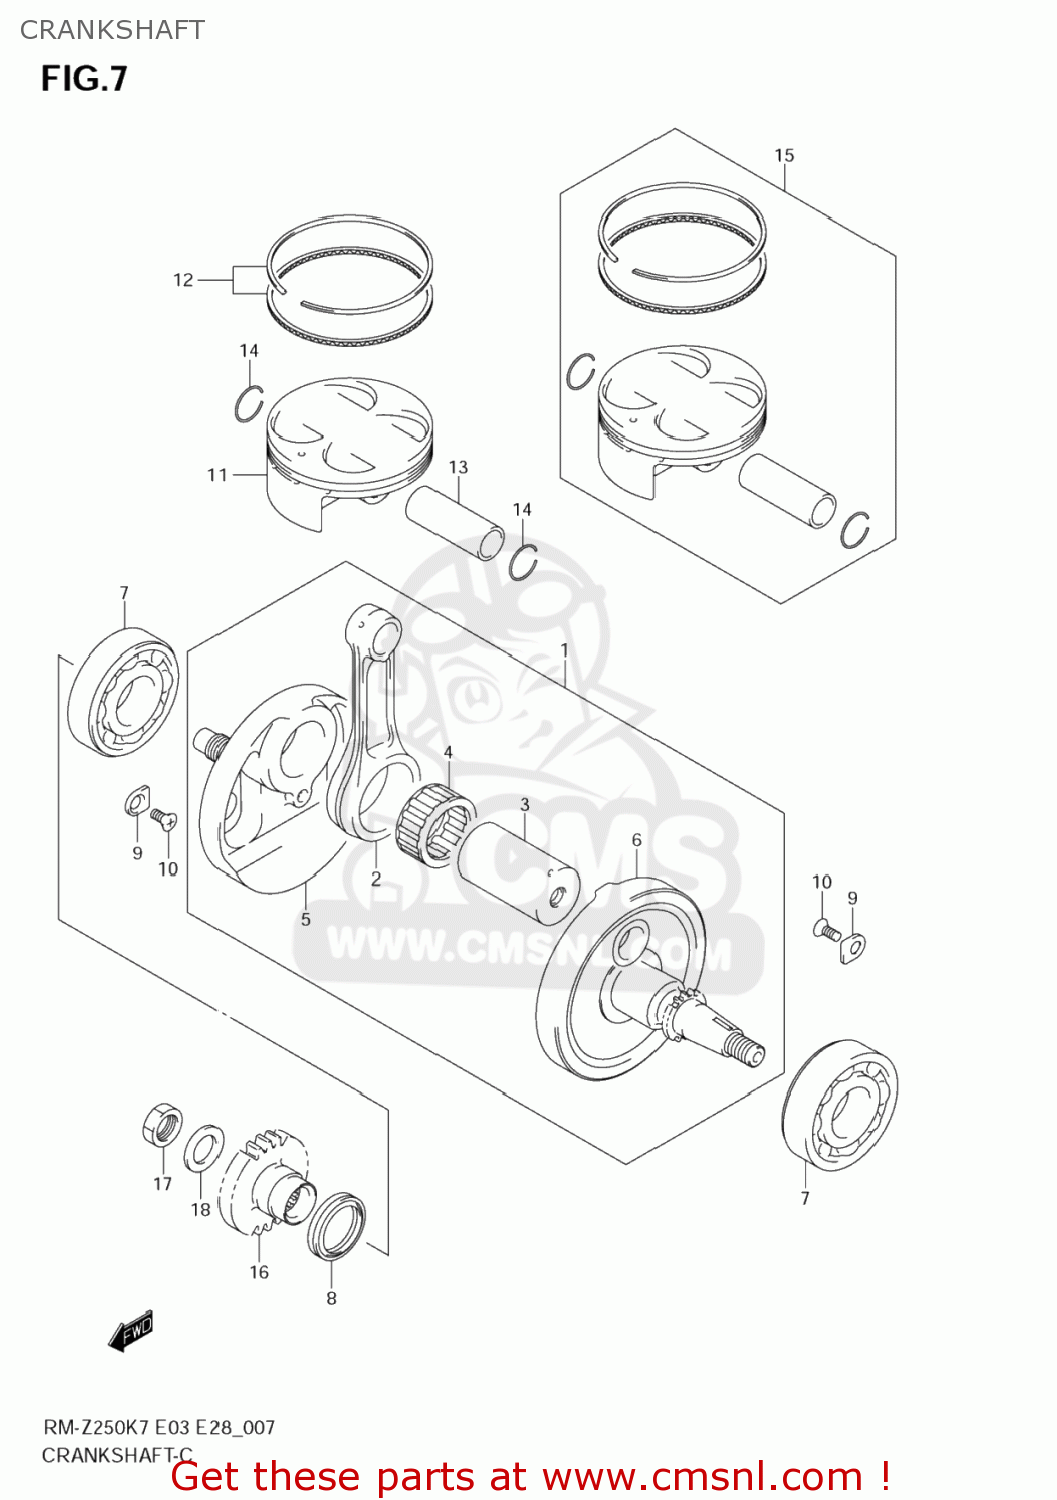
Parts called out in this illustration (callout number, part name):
1	CRANKSHAFT ASS
2	CONNROD
3	PIN,CRANK
4	BEARING
5	CRANKSHAFT,R
6	CRANKSHAFT,L
7	BEARING(30X62X16)
8	SEAL,OIL(30X40X7)
9	RETAINER,CRANKSHAFT BEARING
10	SCREW(6X12)
11	PISTON
12	RING SET,PISTON
13	PIN,PISTON
14	RING,SNAP 16MM
15	PISTON KIT
16	GEAR,PRIMARY DRIVE
17	NUT
18	WASHER
